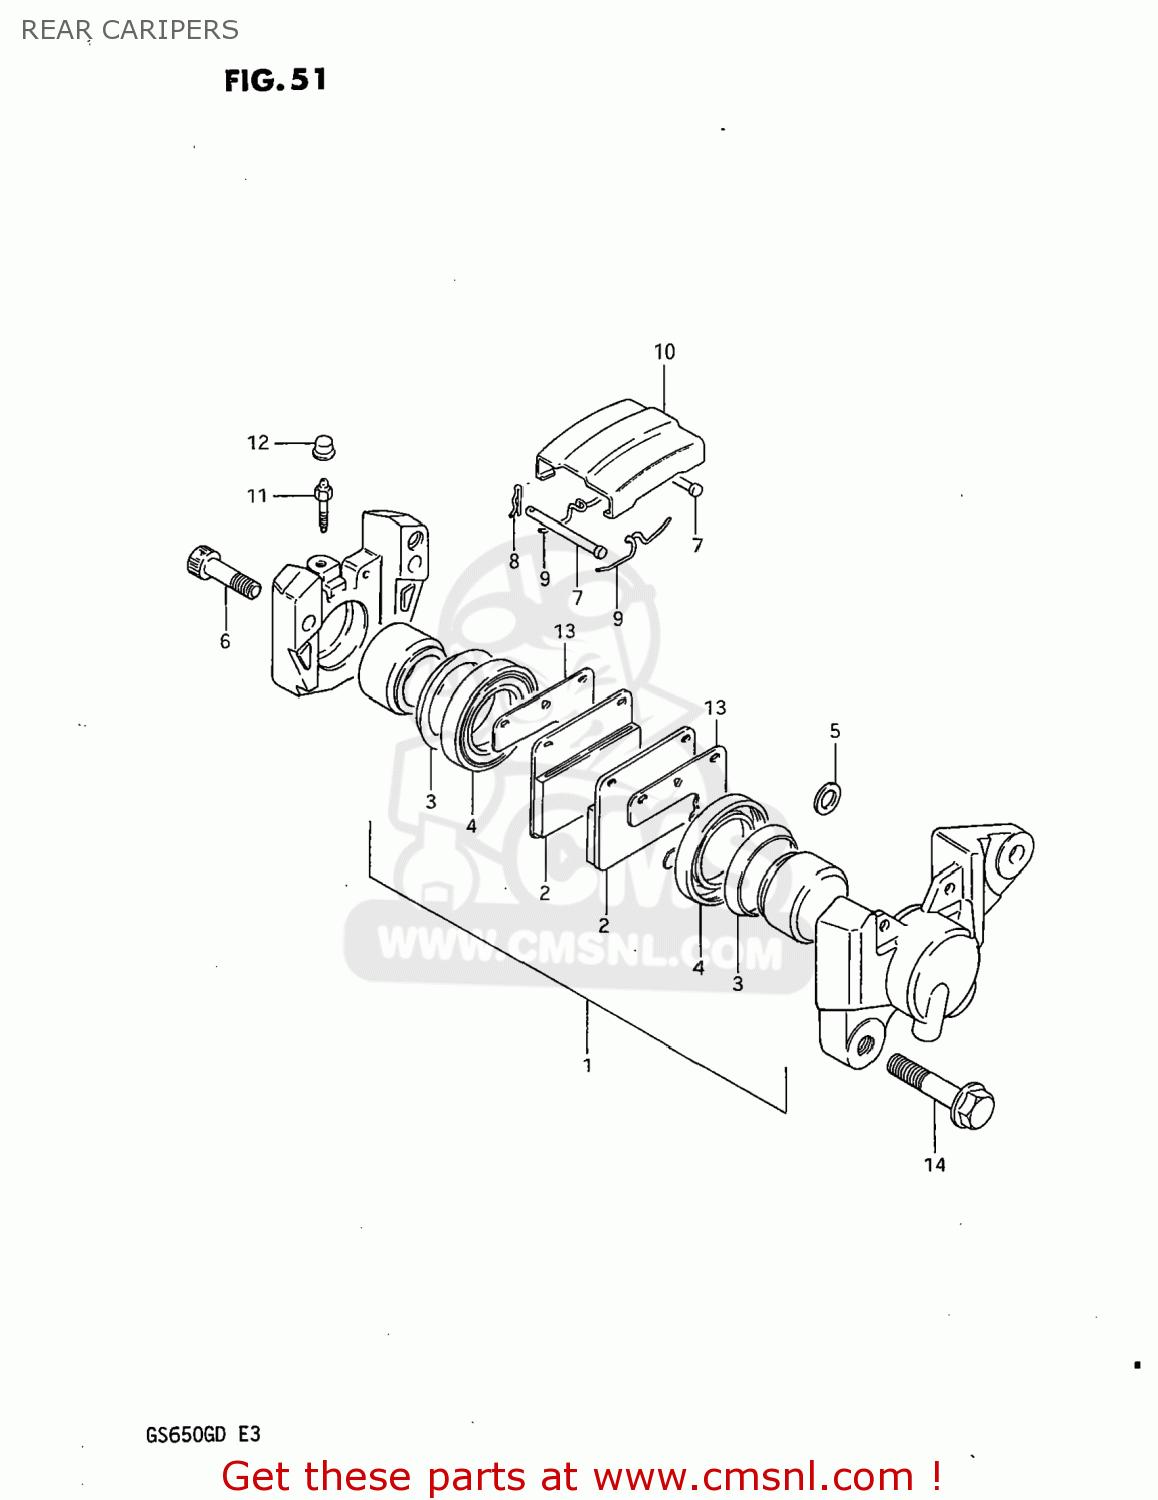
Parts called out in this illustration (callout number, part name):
1	PISTON SET
2	PAD,BRAKE (MCA)
3	SEAL,PISTON
4	BOOT,PISTON
5	SEAL,JOINT
6	BOLT,CALIPER HOUSING
7	PIN,PAD
8	CLIP,PAD PIN
9	SPRING
10	COVER,DUST
11	BLEEDER
12	CAP,BREATHER
13	SHIM,RR CALIPER
14	BOLT
